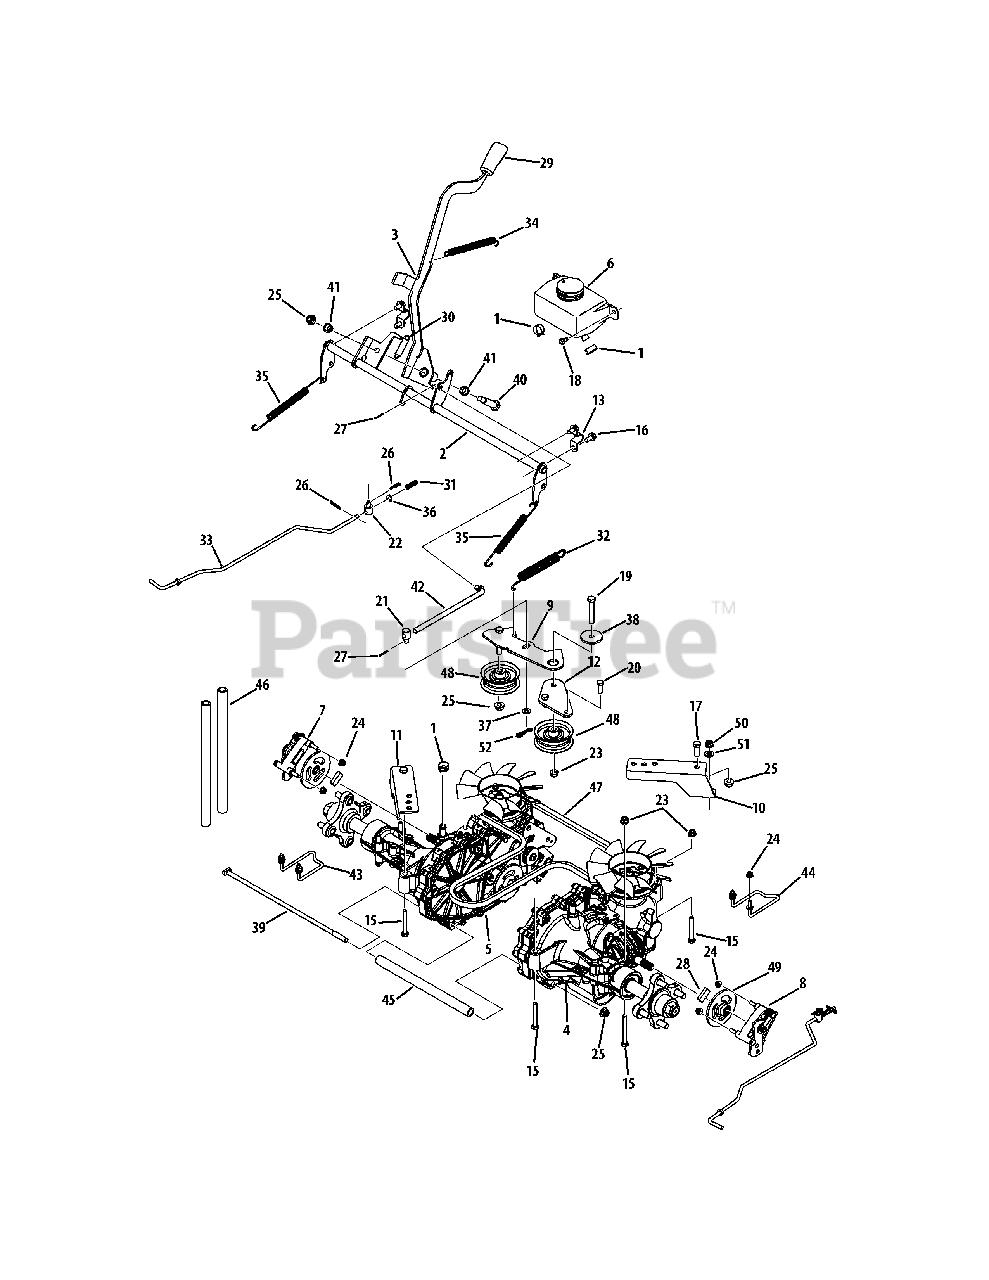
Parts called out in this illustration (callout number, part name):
1	Hose Clamp, 1/2"
2	Brake Shaft Assembly
3	Brake Handle Assembly
4	RH Transmission Assembly
5	LH Transmission Assembly
6	Expansion Tank Assembly
7	LH Brake Assembly
8	RH Brake Assembly
9	Idler Bracket
10	RH Mount Bracket
11	LH Mount Bracket
12	Idler Mount Plate
13	Shaft Mount Bracket
14	Hex Screw, 5/16-18 x 2.75
15	Hex Screw, 5/16-24 x 2.25
16	Hex Washer Screw, 5/16-18 x .750
17	Hex Screw, 3/8-16 x 1.00
18	Hex Washer Screw, 1/4-20 x .500
19	Hex Screw, 3/8-16 x 2.25
20	Hex Screw, 5/16-18 x .875
21	Ferrule, 3/8-24 x .375
22	Ferrule, .325 x .312
23	Flange Lock Nut, 5/16-18
24	Flange Lock Nut, 1/4-20
25	Flange Lock Nut, 3/8-16
26	Cotter Pin, .072 x 1.13
27	Cotter Pin, 3/32 x .750
28	Brake Pad
29	Selector Handle
30	Extension Spring, .48 x 2.03
31	Compression Spring, .405 x 1.17
32	Extension Spring, .75 x 6.02
33	Transmission Bypass Lever Wire
34	Extension Spring, .50 x .6.37
35	Extension Spring, .500 x 7.0
36	Spring Washer, .265 x .562 x .025
37	Thrust Washer, .375 x .70 x .030
38	Shoulder Spacer, .884 x .190
39	Rod, .328 x 14.00
40	Shoulder Screw, .498 x 1.635
41	Flange Bearing, .500 x .34
42	Disenage Brake Rod
43	LH Rod Keeper
44	RH Rod Keeper
45	Transmission Spacer, 10.5
46	Fuel Hose, 1/2 x 12.00
48	Flat Idler Pulley, 2.75
49	Brake Disc
50	Hex Lock Nut, 5/16-24
51	Flat Washer, .330 x .630 x .064
52	Bow-Tie Cotter Pin
